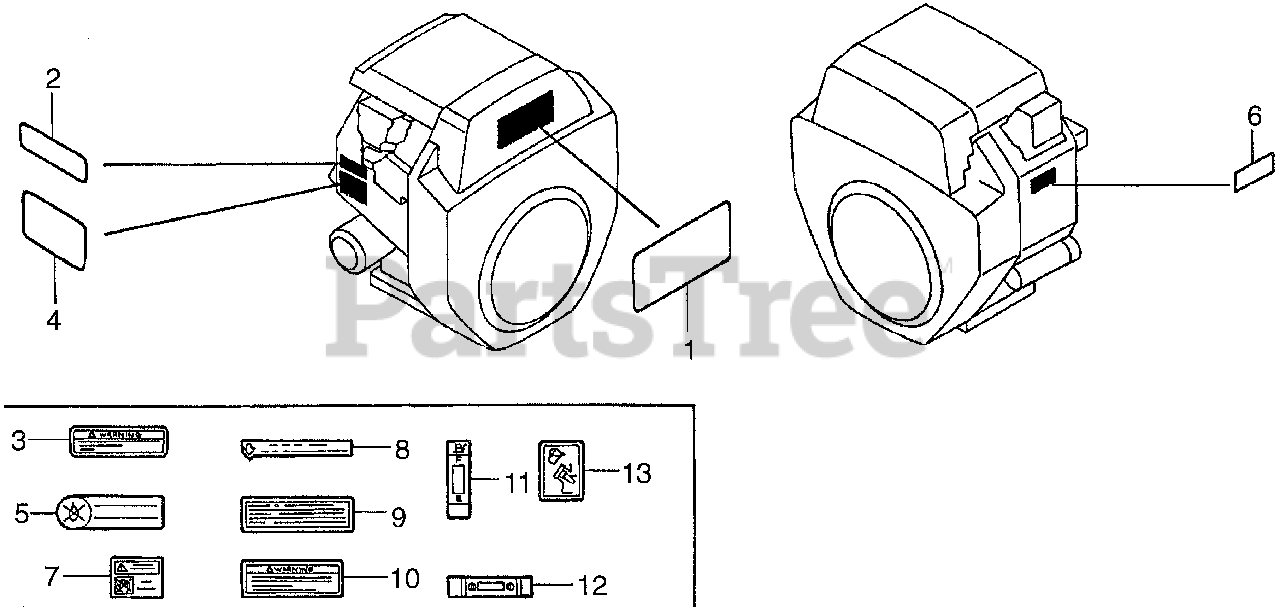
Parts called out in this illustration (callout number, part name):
1	EMBLEM (GX620)
2	LABEL, SPECIFICATION (GX620)
3	LABEL, RAIN WARNING (ENGLISH)
4	LABEL, CAUTION
5	MARK, CAUTION (ENGLISH/FRENCH)(SPANISH)
6	MARK, OIL ALERT (ENGLISH)
7	MARK, EX. WARNING (ENGLISH/FRENCH)
8	MARK, EX. CAUTION
8	MARK, EX. CAUTION (ENGLISH/FRENCH)
9	MARK, CAUTION (CO)(ENGLISH/FRENCH)(SPANISH)
10	LABEL, CONNECT WARNING (ENGLISH)
11	MARK, FUEL METER
12	PLATE, FUEL INDICATION
13	MARK, OIL CAUTION
